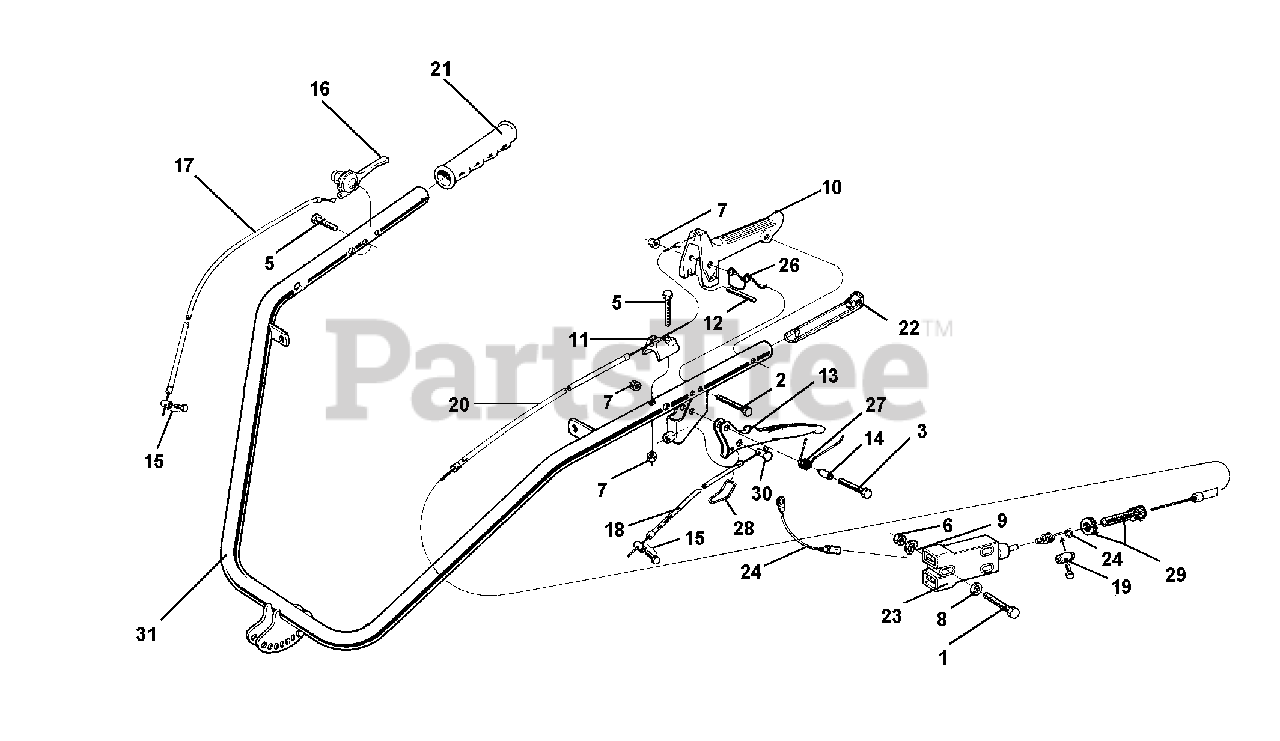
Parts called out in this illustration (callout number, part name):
1	SCREW TE M4 X 25
2	SCREW TE M6 X 45
3	SCREW M6 X 25
4	SCREW M6 X 40
5	SCREW M6 X 35
7	NUT, SELF LOCKING M6
8	FLAT WASHER 4.3
9	LOCK WASHER B 4.3
10	MOTOR STOP LEVER
11	SHEATH STOP OF MOTOR STOP
12	LEVER STOP FOR MOTOR STOP
13	CLUTCH LEVER
14	LEVER SPACER
15	CLAMP, CABLE
16	LEVER, ACCELERATOR
17	CABLE & SHEATH,ACCEL.LOMBAR
18	WIRE AND SHEATH L 903 DISENG.
19	CABLE CLAMP
20	SHEATH CABLE
23	STOP SWITCH
24	SWITCH SPRING
25	SWITCH CAABLES
26	MOTOR STOP LEVER SPRING
27	LEVER SPRING
29	ADJUSTING SCREW
